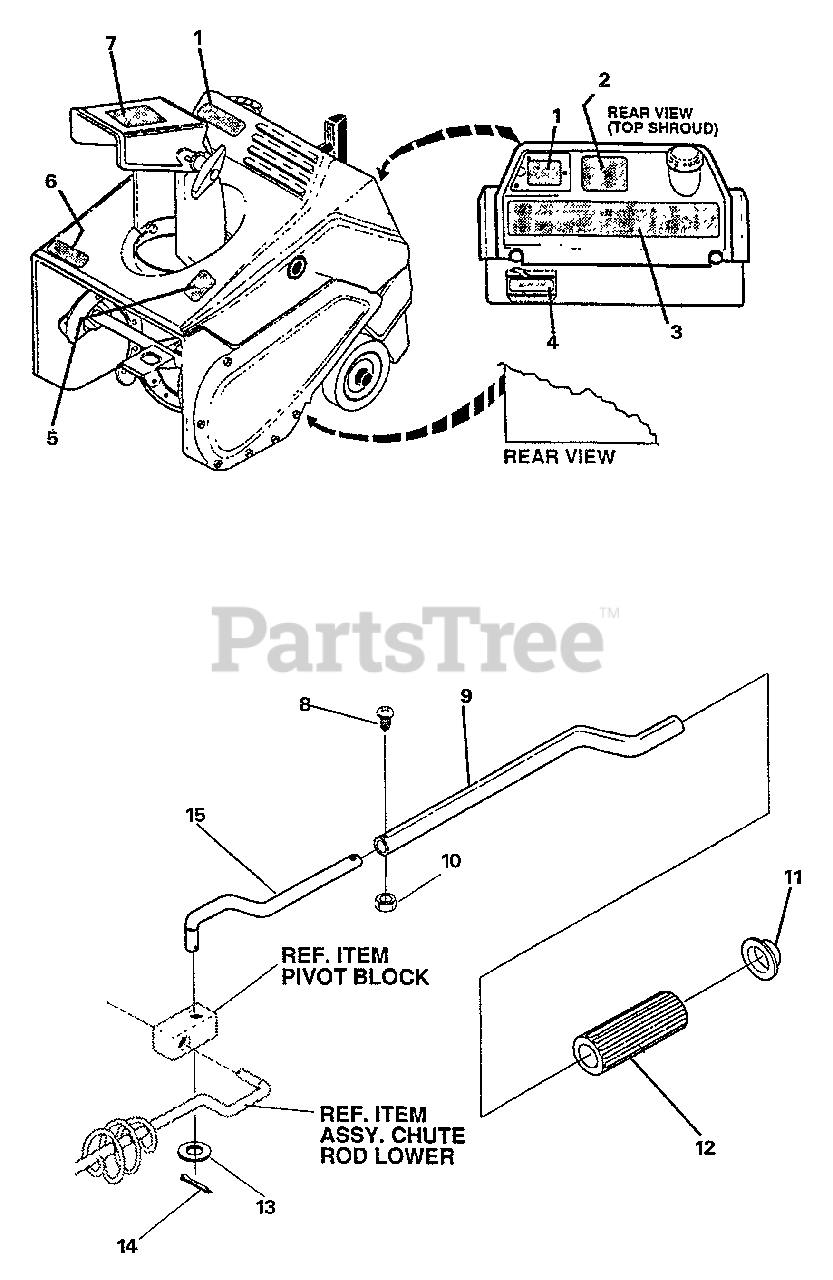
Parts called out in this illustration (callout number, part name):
1	LABEL - ECHO -- ST-5000E
2	LABEL - STARTING
3	LABEL - CONTROL PANEL
4	LABEL - CHOKE
5	LABEL - DANGER
6	LABEL - ECHO
7	LABEL - DANGER
8	SCREW 010-32×0.88
9	ROD, UPPER CHUTE CONTROL
10	NUT
11	NUT, PUSH, FITS 3/8 DIA
13	WASHER - 0.40×0.75×0.025"
14	PIN - COTTER
15	ROD, CHUTE CONTROL MIDDLE
